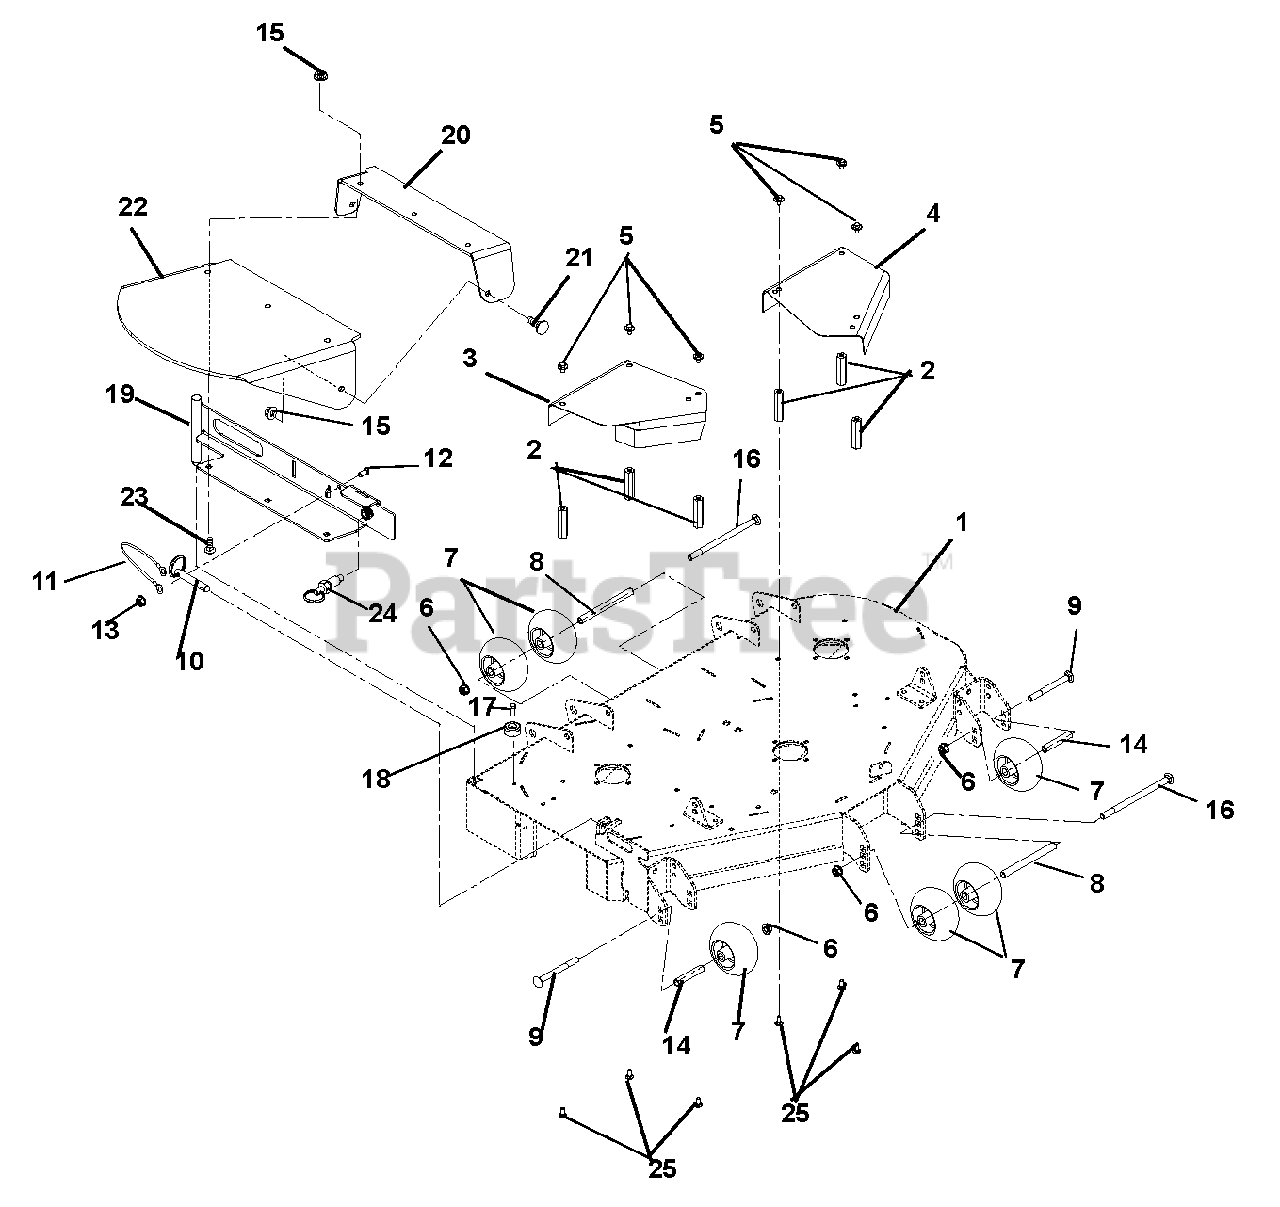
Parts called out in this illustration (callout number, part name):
1	44" Side Discharge Deck Weldment
2	Nut, Coupling .31-18 x 3.00
3	Right Hand Spindle Guard (035)
4	44 in., 48 in., & 52 in. Left Hand Spindle Guard
5	Bolt, SEMS .31-18 x .62
6	Nut .50-13 Nyloc Flange
7	Anti-Scalp Wheel
9	Bolt, Round Head Square Neck .50-13 x 5.00
10	Pin, Spring Ball .375 OD x 1.50
11	Cable, 6.0 Lanyard, Nylon
12	Bolt, Hex .25-20 x .75 Grade 5
13	Nut, Locking Top Flange .25-20
14	Spacer, .510 x .625 x 3.35
15	Nut, .38-16 Nyloc Flange
16	Bolt, Round Head Square Neck .50-13 x 8.50
17	Screw, Tapping .31-18 x .75 Hex Washer Head Thread
18	Bumper, Recessed 1.50 x .63 , .31 Thru Hole
19	44 in. & 48 in. Discharge Chute Mounting Weldment
20	Rubber Discharge Chute Support
21	Bolt, Round Head Square Neck .38-16 x 1.00 Grade 5
22	Chute, Rubber Discharge
23	Bolt, Round Head Square Neck .38-16 x 1.25 Grade 5
24	Pin, Pull
25	Bolt, Round Head Square Neck .31-18 x .75
